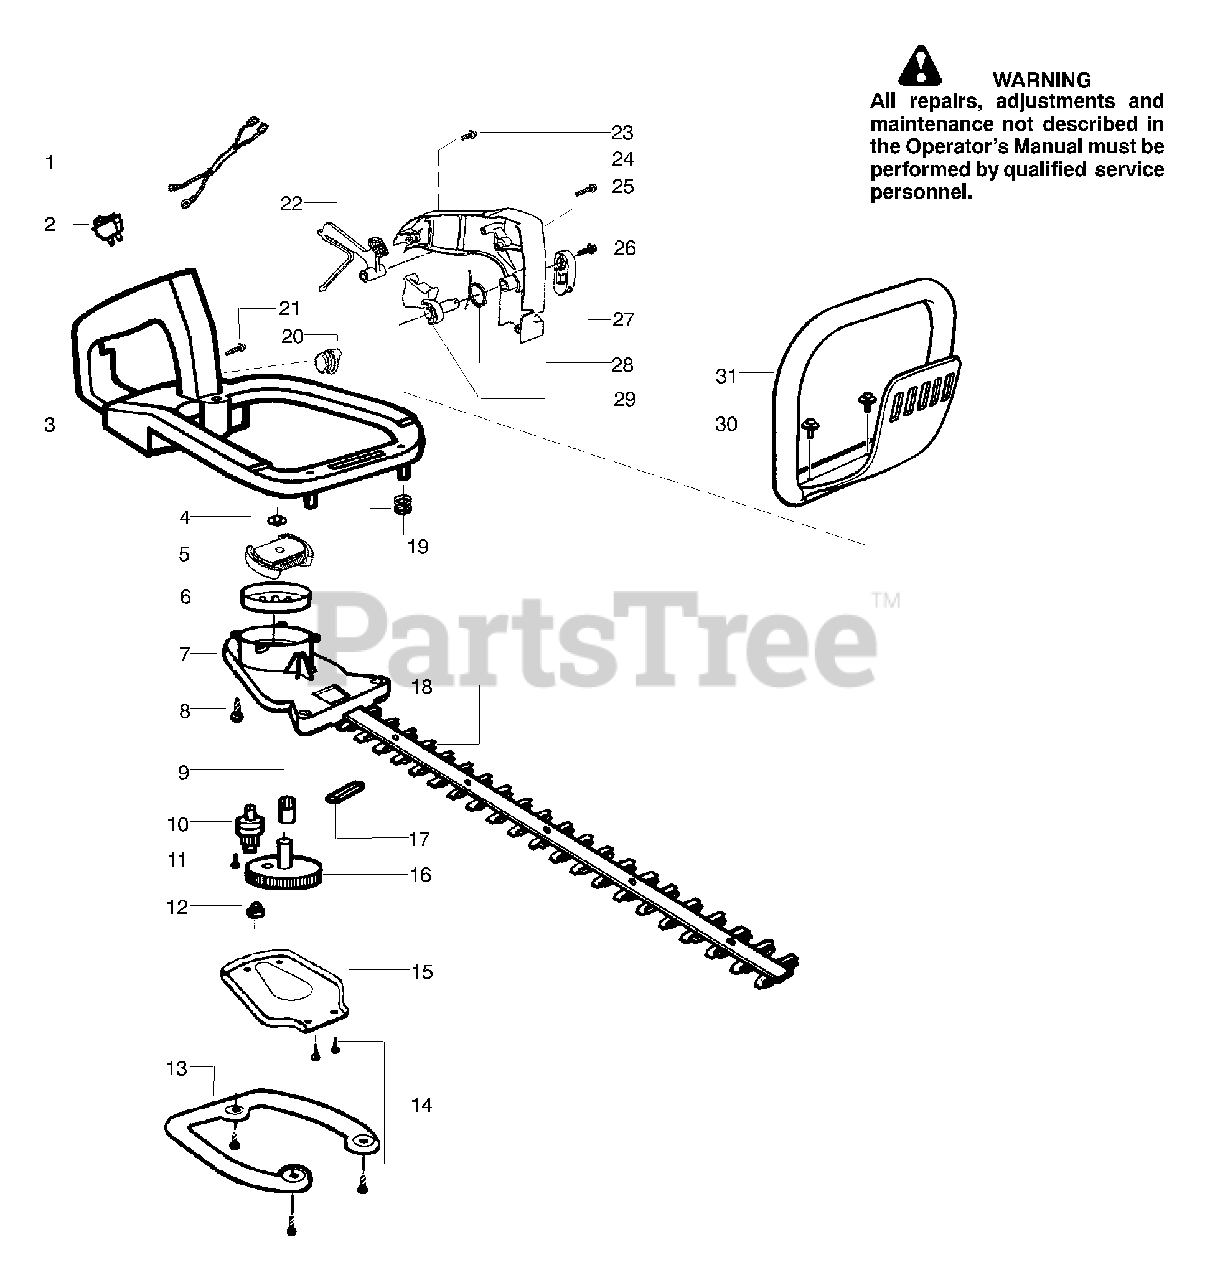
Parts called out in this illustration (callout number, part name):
1	Assy-Leadwire/Switch
2	Switch-Ignition
3	Assy-Rear Handle & Tank
4	Washer-Clutch
5	Kit-Clutch Assy.
6	Assy-Drum
7	Assy-Gear Box
9	Bearing-Gear
10	Assy-Pinion
11	Screw
12	Bushing-Blade
13	Plate-Isolator
15	Cover-Gear Box Plate
16	Kit-Drive Gear Ass'y.
17	Seal-Blade (Felt)
18	Assy-Blade 19"
20	Assy-Fuel Cap
22	Lockout-Throttle
24	Cover-Handle
27	Lever-Trigger
28	Spring-Trigger
31	Handle-Front
